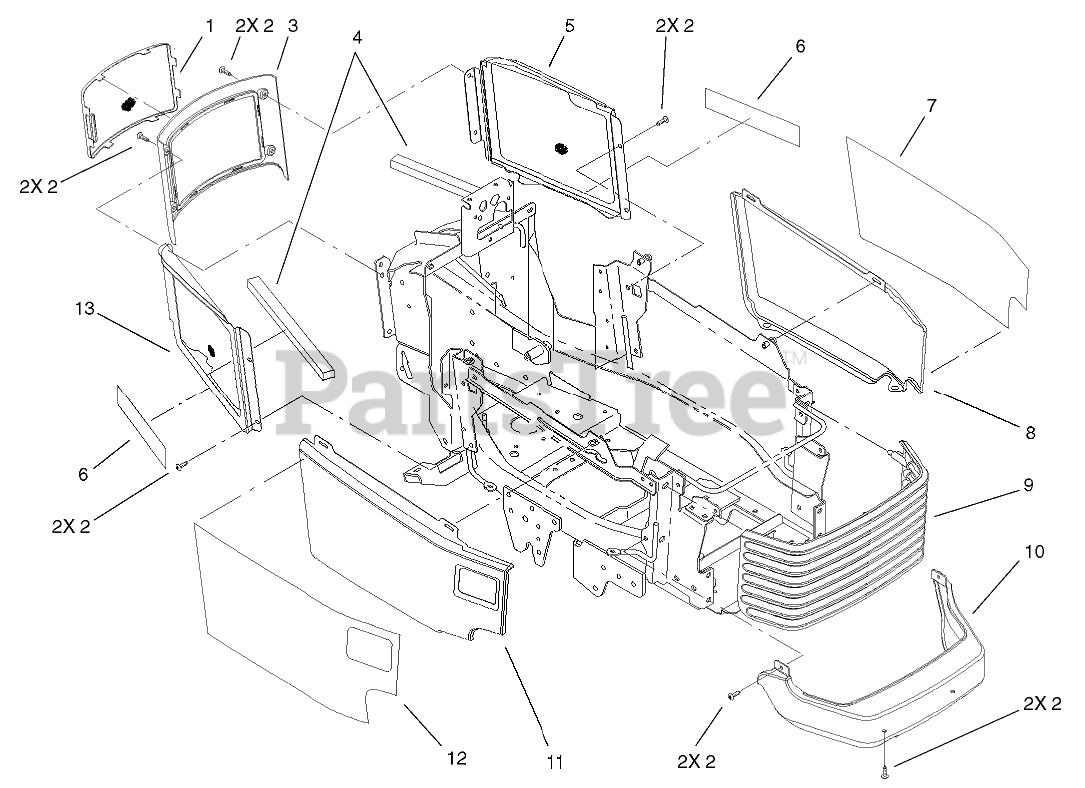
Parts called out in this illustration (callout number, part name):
1	SCREEN-REAR
2	SCREW-HH
3	COVER-REAR
4	FOAM-SEAL, SIDE SCREEN
5	Cover-Side LH
6	Decal-522 Xi
7	Decal-Hood, LH
8	PANEL-SIDE, LH HOOD
9	GRILL
10	COVER-BUMPER
11	PANEL-SIDE, RH HOOD
12	Decal-Hood, RH
13	Cover-Side, RH
